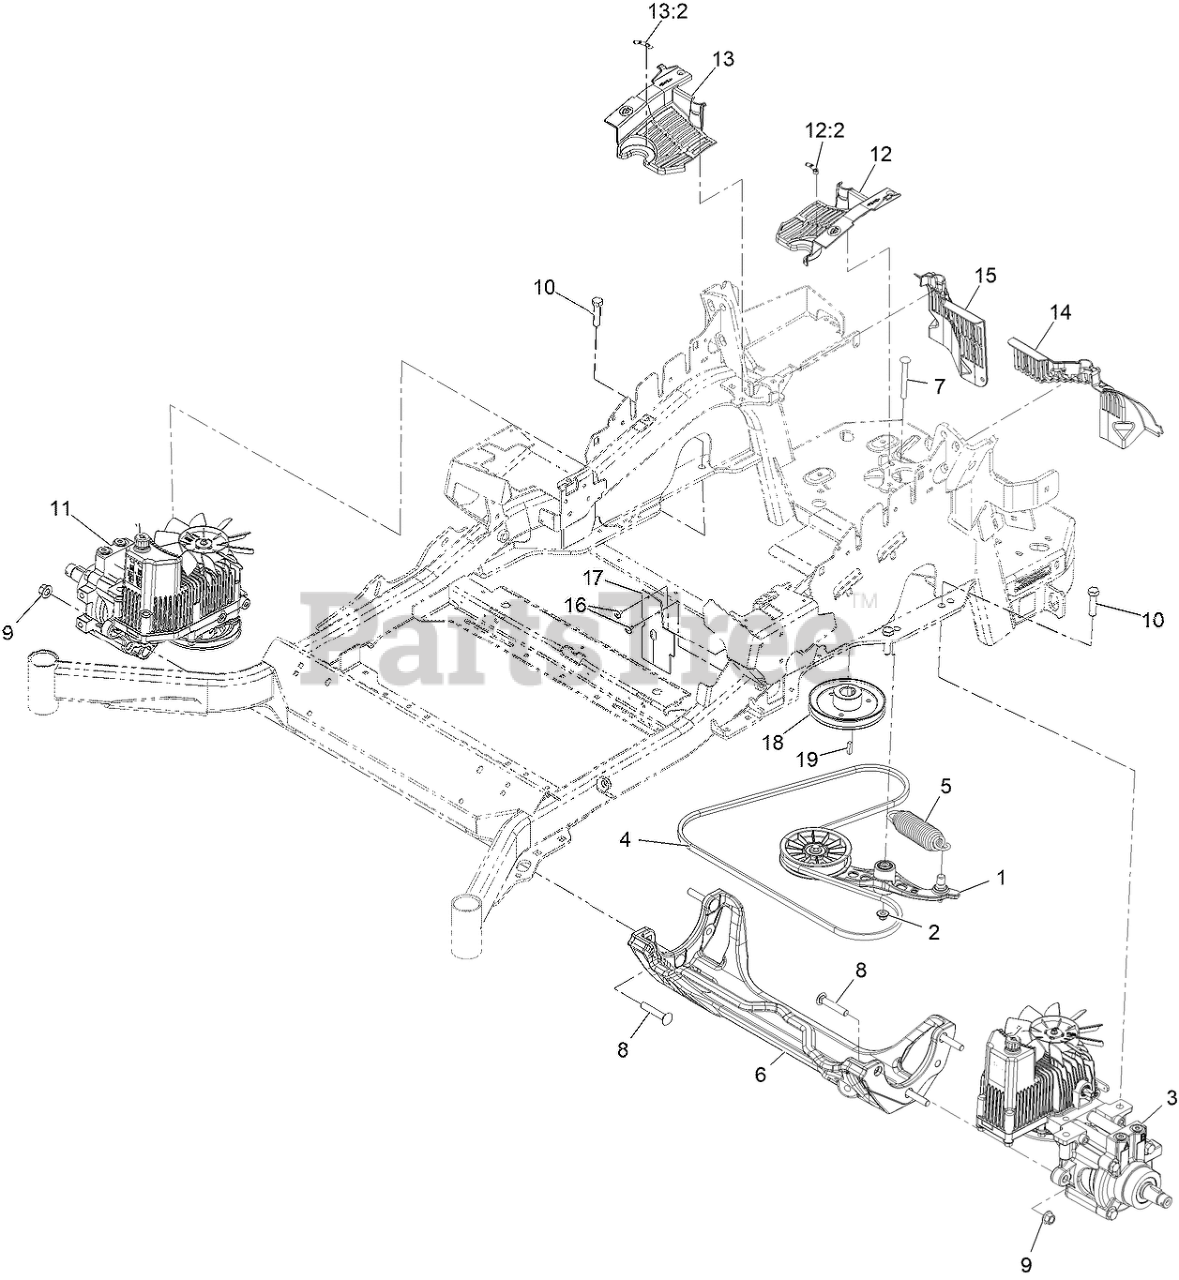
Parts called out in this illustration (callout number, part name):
1	PUMP IDLER ASM
2	Nut-Nyloc 3/8-16 Flg
3	HYDRO-LH
5	SPRING-EXTENSION
6	CRADLE-HYDRO
7	BOLT-SHOULDER, CARRIAGE 3/8-16 X 3 1/2
8	SCREW-CARR
9	Nut-Lock 1/2-13
10	SCREW-HH
11	HYDRO-RH
12	LH HYDRO GUARD ASM
12:2	DECAL-OIL, HYDRO
13	RH HYDRO GUARD ASM
13:2	DECAL-OIL, HYDRO
14	GUARD-HYDRO REAR, LH TRIM
15	GUARD-HYDRO, REAR (RH)
16	RIVET-POP
17	DEFLECTOR-AIR FLOW
18	SHEAVE
